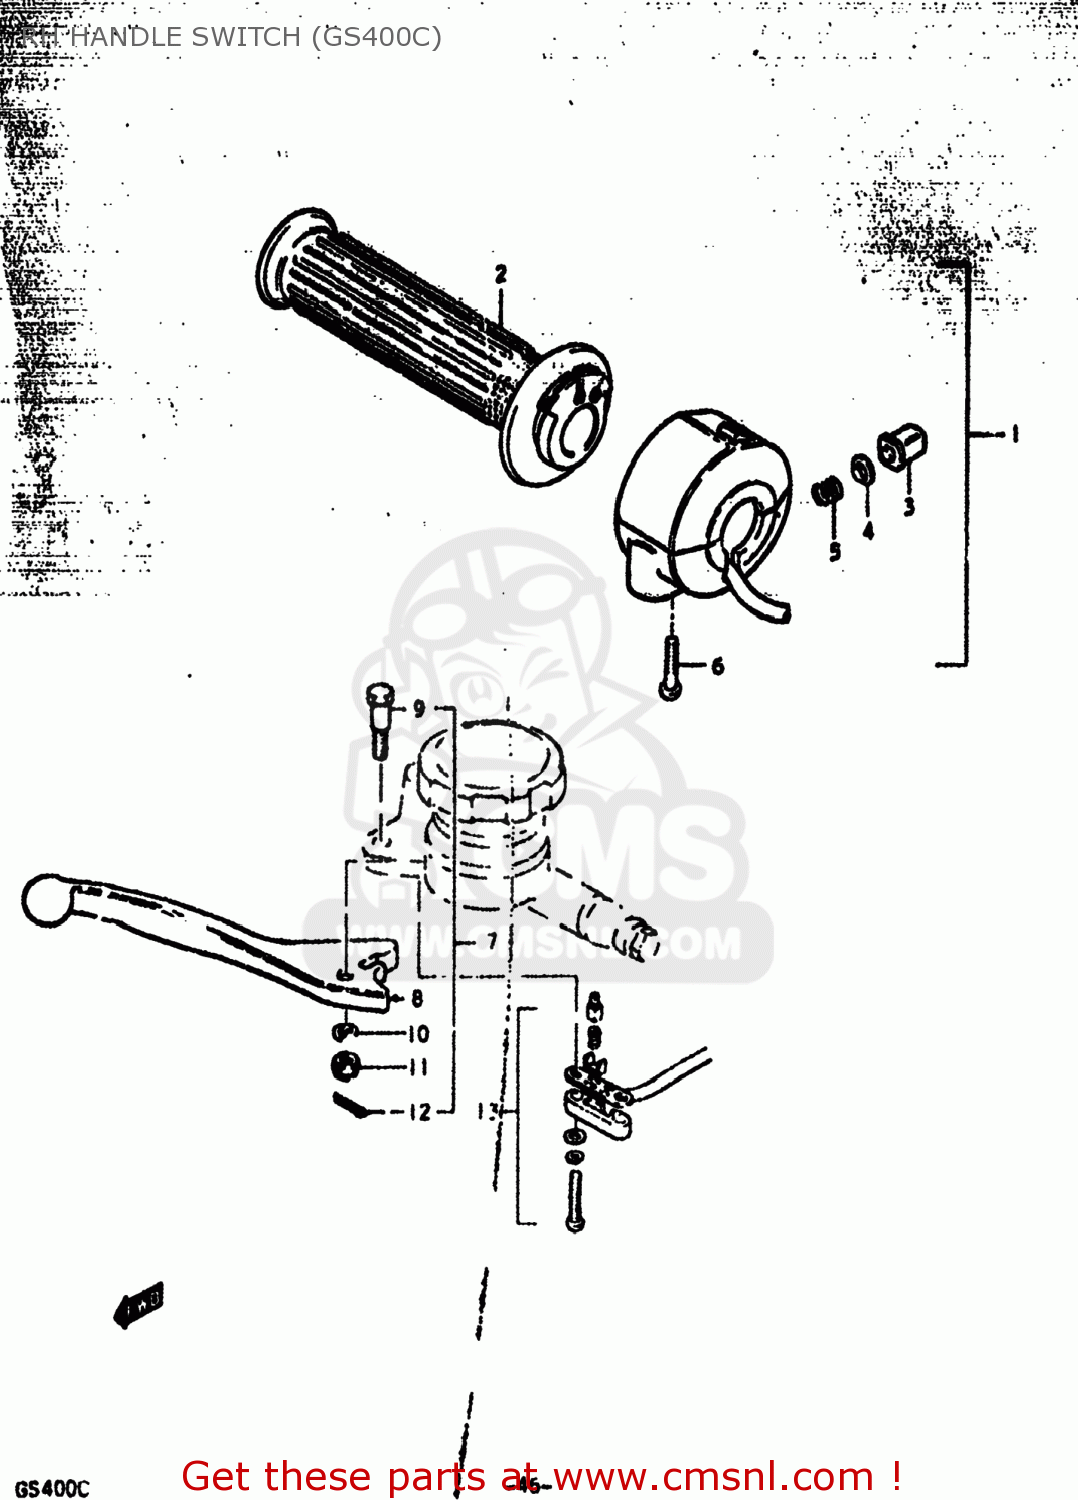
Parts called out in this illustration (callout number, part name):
1	CASE ASSEMBLY,THROTTLE
2	GRIP,THROTTLE
3	BUTTON,HORN
4	CONTACT
5	SPRING
6	SCREW
7	LEVER ASSEMBLY,BRAKE
8	LEVER,BRAKE
9	BOLT,LEVER
10	LOCK WASHER
11	NUT,LEVER FITTNG
12	COTTER PIN
13	SWITCH ASSY,STOP
